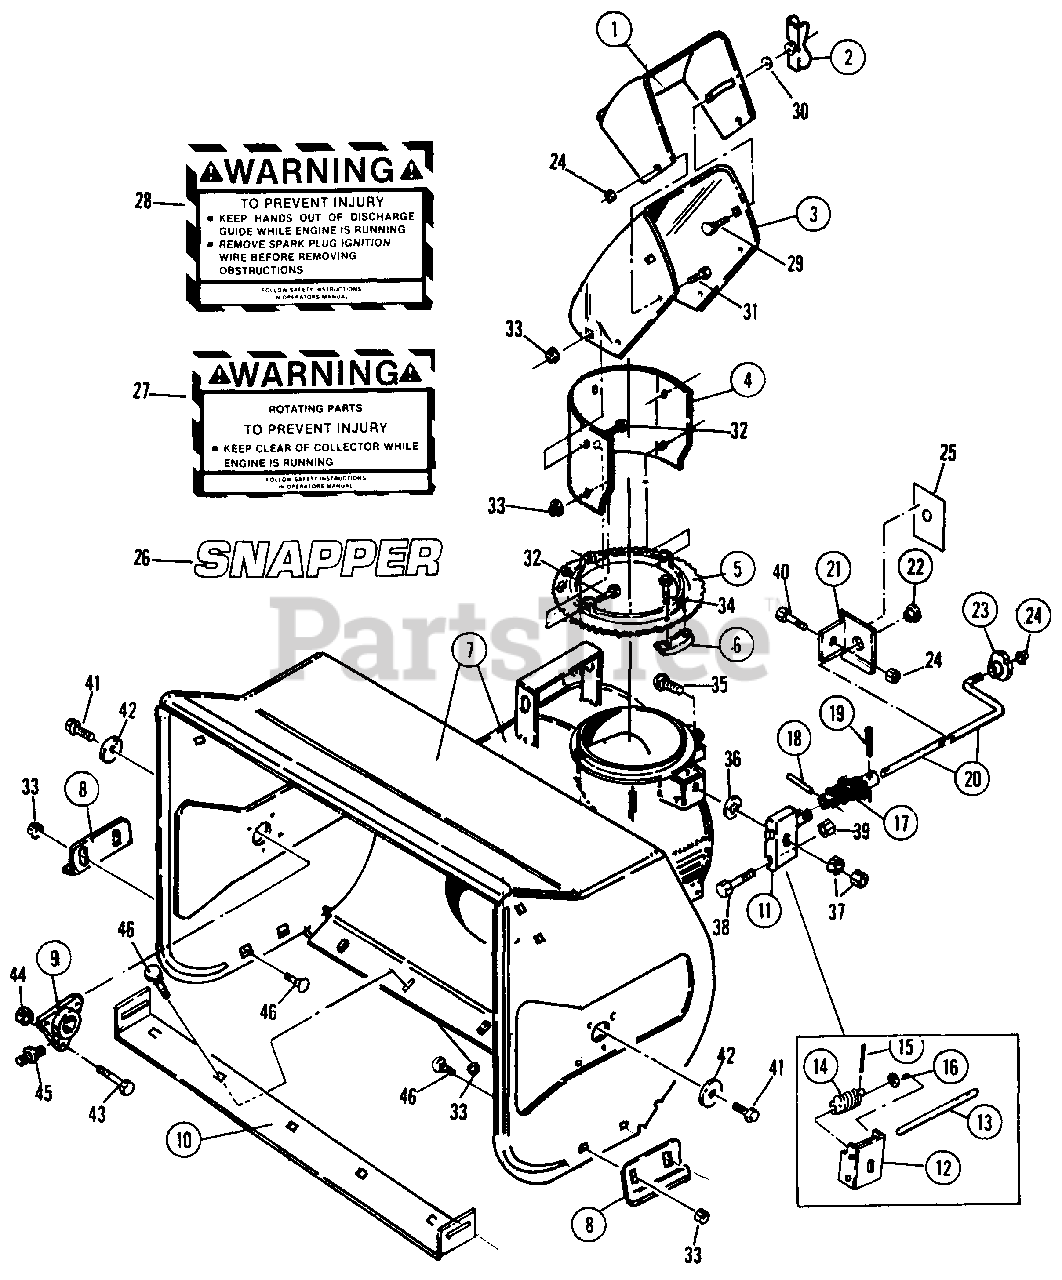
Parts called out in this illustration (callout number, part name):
1	DEFLECTOR
2	WING-NUT
4	EXTENSION, Chute
5	RING, Chute
6	RETAINER, Chute Ring
7	HOUSING,Blower
8	SHOE, Skid
9	BEARING, Auger Shaft
10	BLADE, Scraper
11	ASSEMBLY, Worm Bracket
12	BRACKET, Worm
13	SHAFT, Worm
14	WORM
15	ROLL-PIN, 1/8x3/4
16	WASHER, Spring Steel
17	UNIVERSAL JOINT
18	PIN, 1/8" x 1" Roll
19	COTTER-PIN, 1/8x1
20	CRANK, Chute
21	BRACKET, Chute Crank
22	BUSHING, Crank
23	KNOB, Chute Crank
24	LOCK NUT, 5/16C
25	DECAL, Chute Control
26	DECAL, SNAPPER
27	DECAL, Collector Warning
28	DECAL, Deflector Warning
29	BOLT, 1/4Cx3/4 Carriage
30	WASHER, 1/4 SAE Flat
31	SCREW, 5/16Cx1/2, Hex Head Cap
32	BOLT, 5/16-18x1/2 Gr.5 Carriage
33	NUT, 5/16-18 Flange
34	SCREW, 10Cx1/2 Hex Hd Self Tap.
35	BOLT, 5/16Cx1 Carriage
36	RETAINER, Bolt
37	NUT, 5/16C Hex
38	SCREW, 5/16-24x2-1/2 Hex Head Cap
39	LOCK NUT, 5/16-24 Hex
40	SCREW, 5/16-18x5/8 Hex Head Cap
41	SCREW, 3/8Cx1/2 Self Tap.
42	WASHER, 3/8" Flat
43	BOLT, 1/4Cx5/8 Hex Flange Lock
44	NUT, 1/4C Hex Flange
45	LUBE FITTING, Straight (press-fit for .187 dia. Hole)
46	BOLT, 5/16-18x3/4 Carriage
